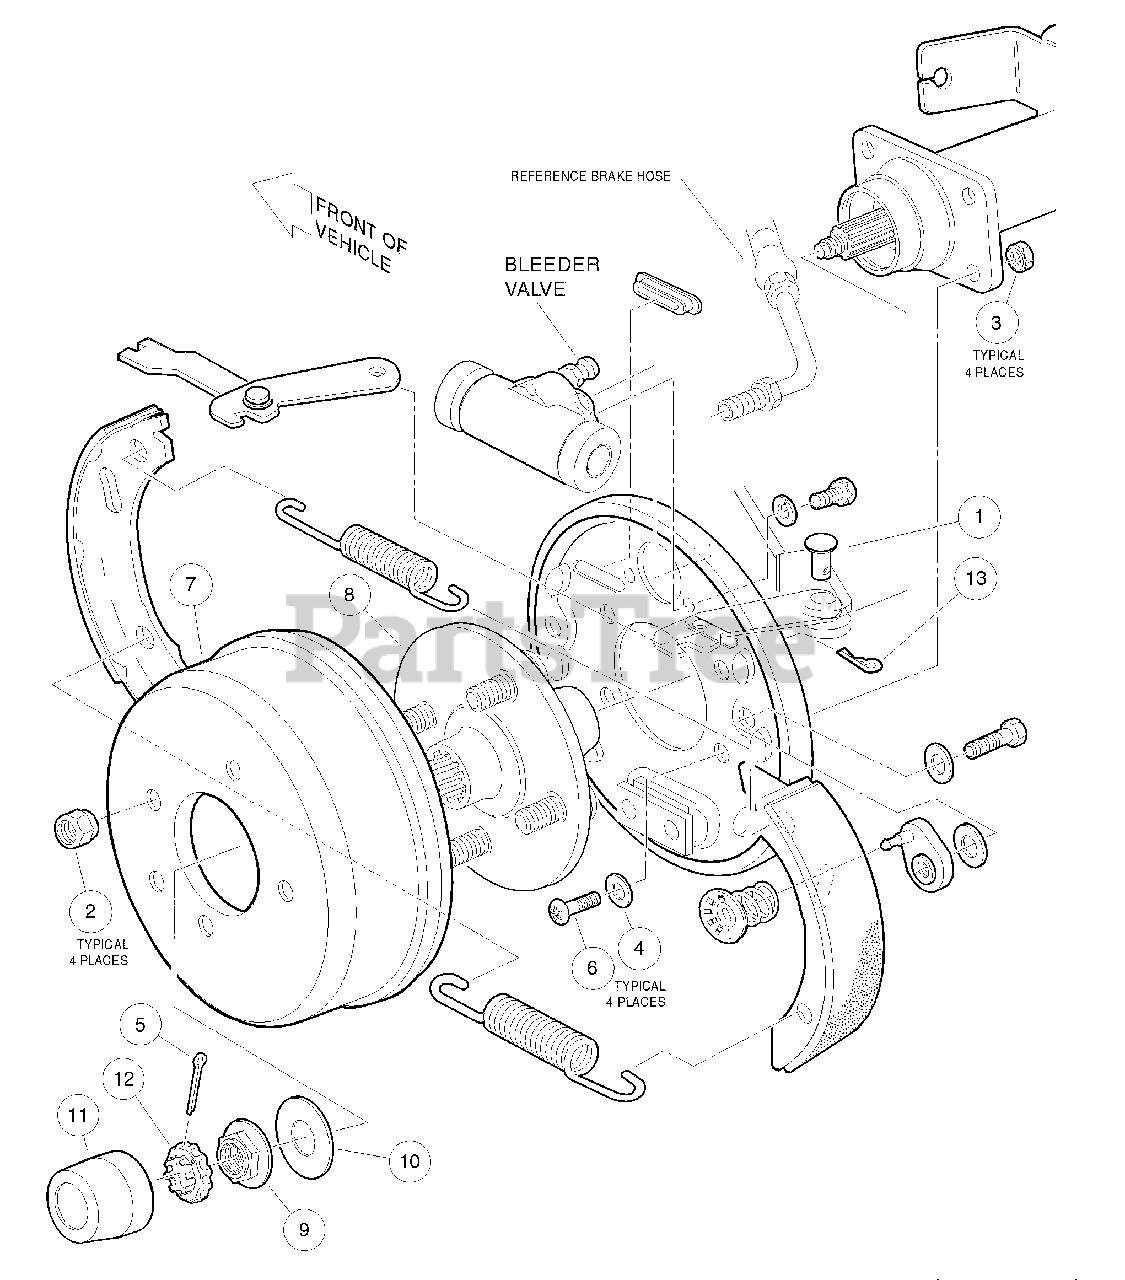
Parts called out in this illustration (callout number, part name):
1	Pin, Clevis, 5/16 X 3/4
2	500-20 Unf Lug Nut
3	Nut, 5/16-24 Hex Head Cone
4	Washer, 5/16 Hardened
5	Pin, Cotter, 0312 x 125
6	Screw, 5/16-24 X 10 Torx Hd
7	Brake Drum
8	Wheel Bolt Flange
9	Nut, Flange
10	Washer - Axle
11	Center Cap, Rubber
12	Locking Cap, Nut
13	Pin, Bow Tie Locking - 072
